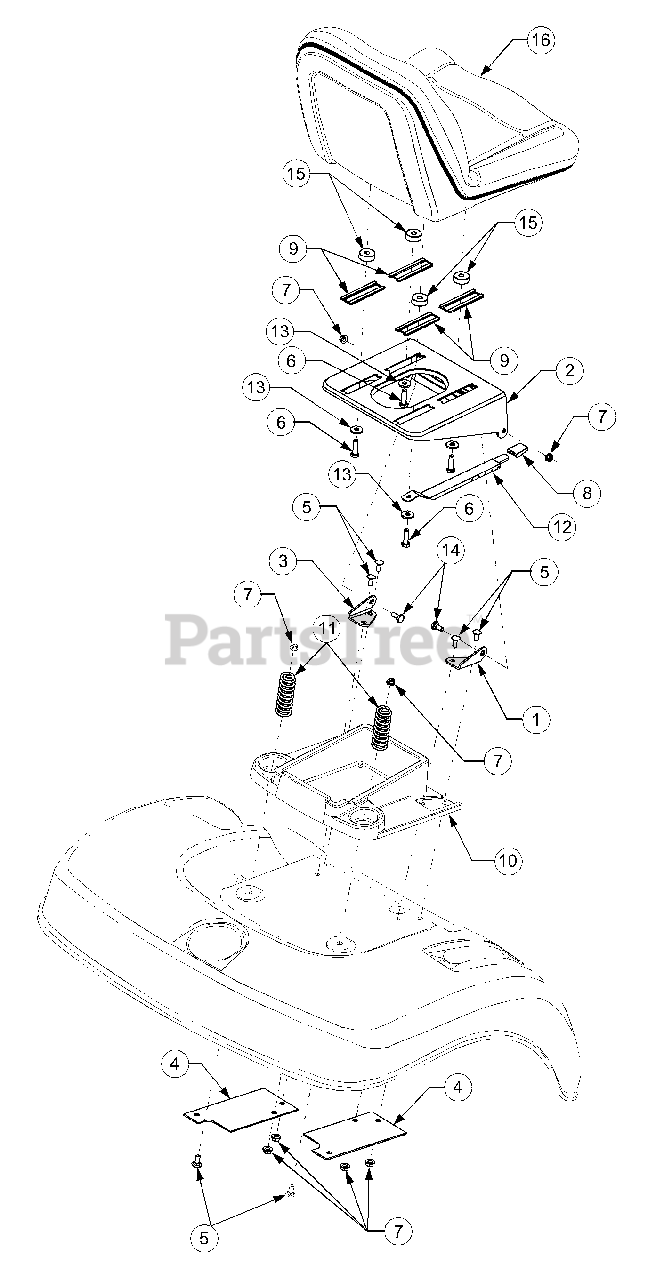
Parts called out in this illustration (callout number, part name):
6	Screw, Hx Cap Lock, 3/8-16 x 1.25 GR5
7	Nut, Hex Flange Lock, 5/16-18
8	Knob, Seat Adjuster
9	Slide, Seat
10	Tray, Tool
11	Spring, Comp, 1.9 OD x 2.4
12	Index Spring, Seat Adjuster
13	Washer, Flat, .406 x 1.0 x .105
14	Bolt, Shoulder
15	Spacer, Seat Slide Shoulder
16	Seat, High Back
